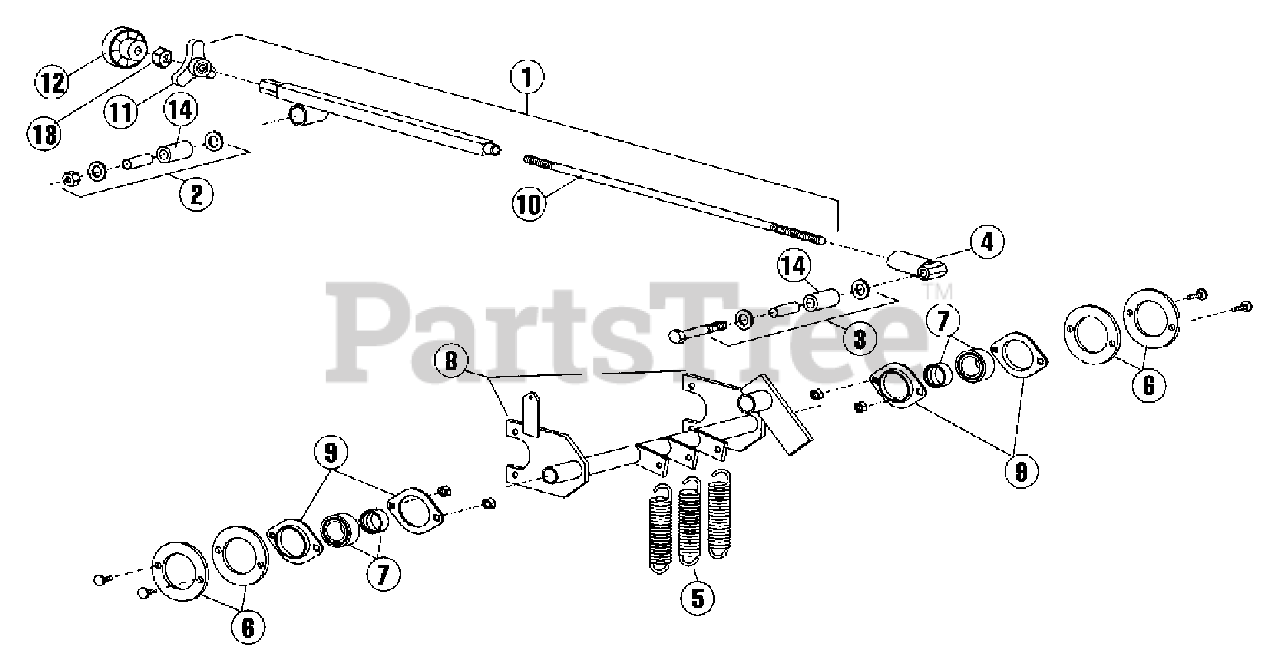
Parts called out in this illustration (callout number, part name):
1	Depth adjuster assembly control
2	Fastener kit, upper depth, adjustment assembly
3	Fastener kit, lower depth, adjustment assembly
4	Rod end, coupler, depth control
5	Spring, blade lift
6	Spacer, bearing
7	Bearing, 1" with locking collar
8	Trunnion assembly
9	Stamping kit
10	Depth adjust screw
11	Knob, three prong (depth lock)
12	Knob, depth
13	Nut, hex, jam, 1/2-13
14	Bushing, polyurethane
